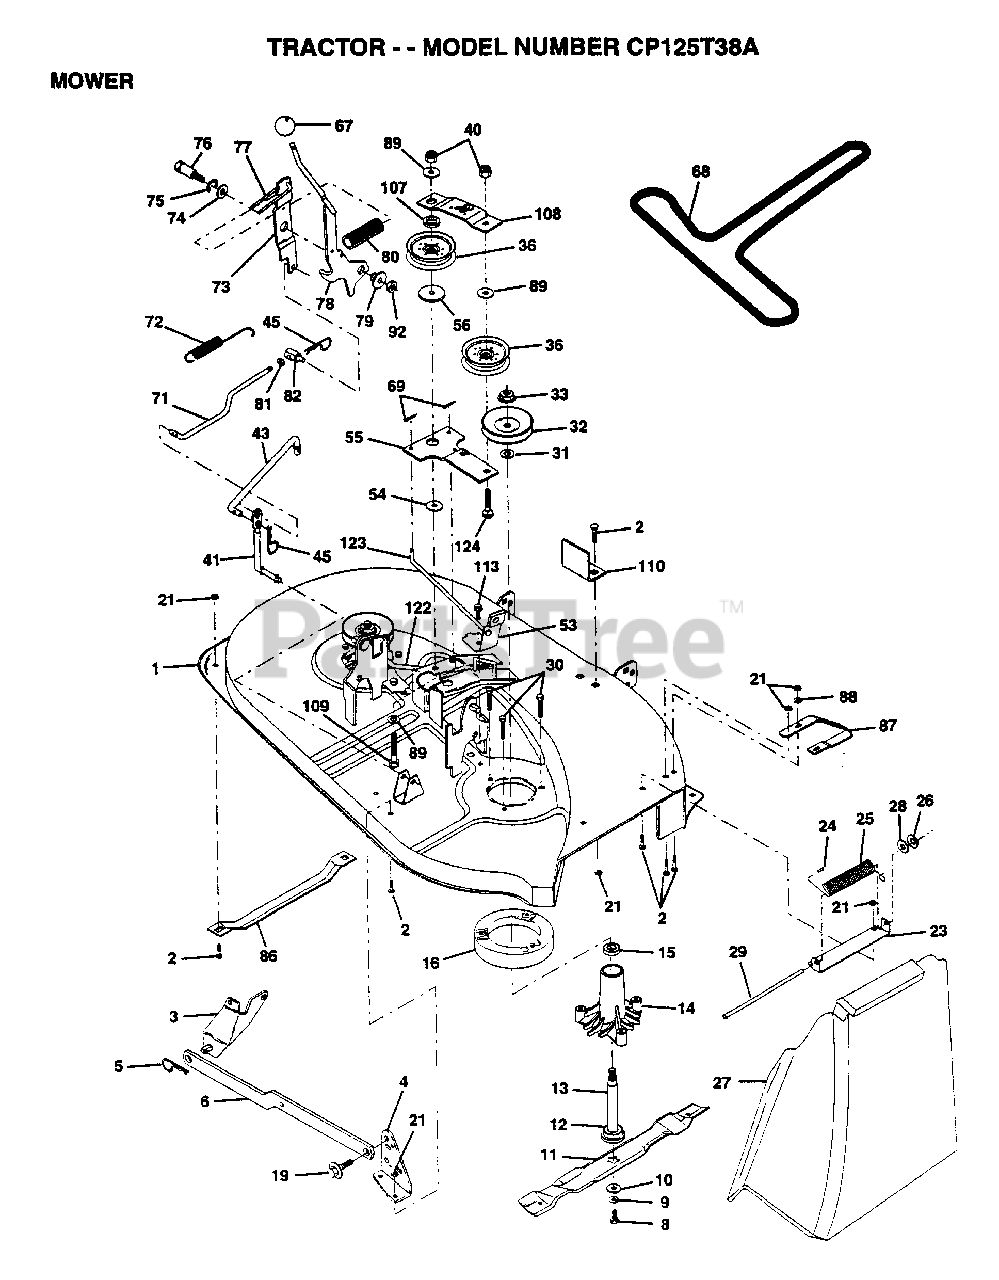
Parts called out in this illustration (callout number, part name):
2	BOLT
3	BRKT ASM SWAY BAR
4	BRKT DECK SW BAR
8	BLADE BOLT
10	WASHER.HARD.BLADE
11	"BLADE.38"" HIPERF"
12	BEARING.BALL
14	HSG ASM MANDREL
15	BEARING
16	STRIPPER RND MWR
19	BOLT SHD 5/16-18
23	BRKT DEFLECTOR
24	CAP-SLEEVE LT
25	SPRING TORSION
26	NUT PUSH M
27	DEFLECTOR-SHLD T
28	WASHER
29	ROD-HINGE T
31	WASHER
36	FLAT IDLER PULLEY
41	PIVOT ROD
43	CLUTCH ROD SECOND
45	RETAINER M
53	BRAKE ASM
54	HARDENED WASHER
55	IDLER ARM ASSY
56	SPACER RETAINER
67	KNOB T(3/8 HOLE)
68	V BELT
71	ROD CLUTCH 38/42
72	RETURN SPRING
73	CLUTCH ARM SECOND
74	WASHER
75	RING
76	SHOULDER BOLT
77	SPRING KEEPER
79	BUSHING
81	NUT
82	TRUNION ADJ
86	RUNNER-LH M
87	RUNNER RH
88	WASHER M
89	WASHER GT
92	NUT
107	RETAINER SPACER
108	IDLER ARM STIFF
109	BOLT
110	UPSTOP DECK FT 38
113	SCREW
122	BRAKE ROD LH
123	BRAKE ROD RH
124	BOLT
